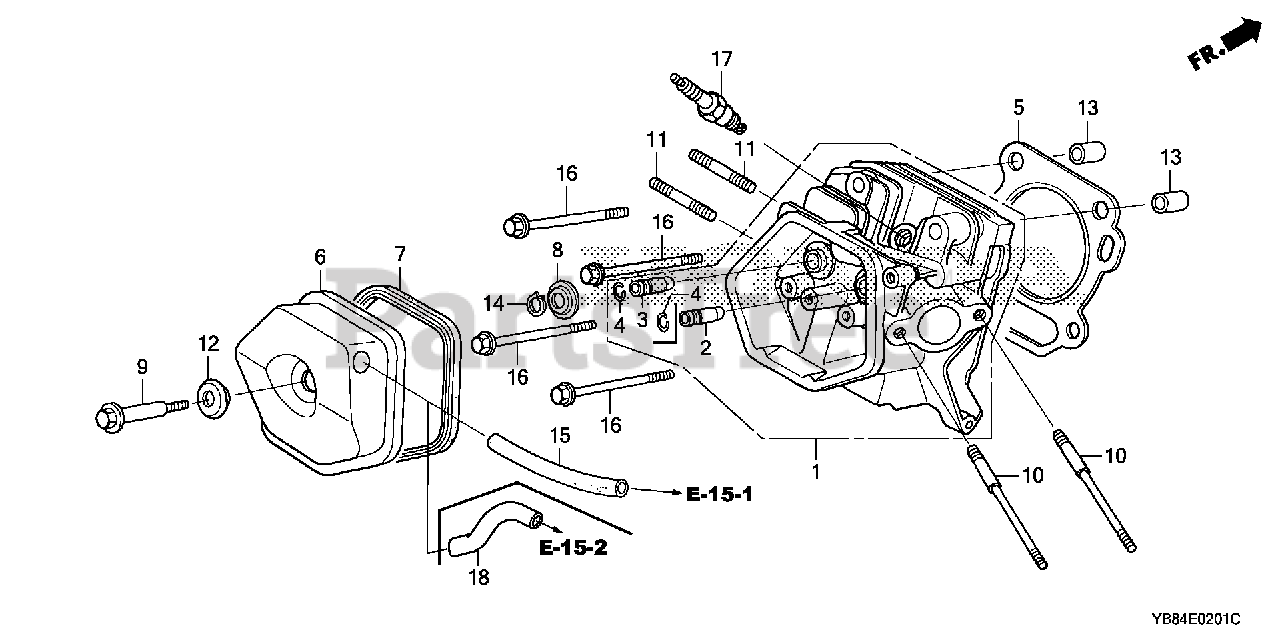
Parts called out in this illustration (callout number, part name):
1	CYLINDER HEAD
2	GUIDE, VALVE (OVER SIZE)
3	GUIDE, EX. VALVE (OVER SIZE)
4	CLIP, VALVE GUIDE
5	GASKET, CYLINDER HEAD
6	COVER, HEAD
7	GASKET, HEAD COVER
8	SEAT, VALVE SPRING
9	BOLT, HEAD COVER
10	BOLT, STUD (8X123)
11	BOLT, STUD (8X32)
12	WASHER, HEAD COVER
13	PIN, DOWEL (12X20)
15	BULK HOSE, VACUUM (11X1000) (11X100)
16	BOLT, FLANGE (10X80)
17	SPARK PLUG (BPR5ES) (NGK)
17	SPARK PLUG (W16EPR-U) (DENSO)
17	SPARK PLUG (BPR6ES) (NGK)
17	SPARK PLUG (W20EPR-U) (DENSO)
